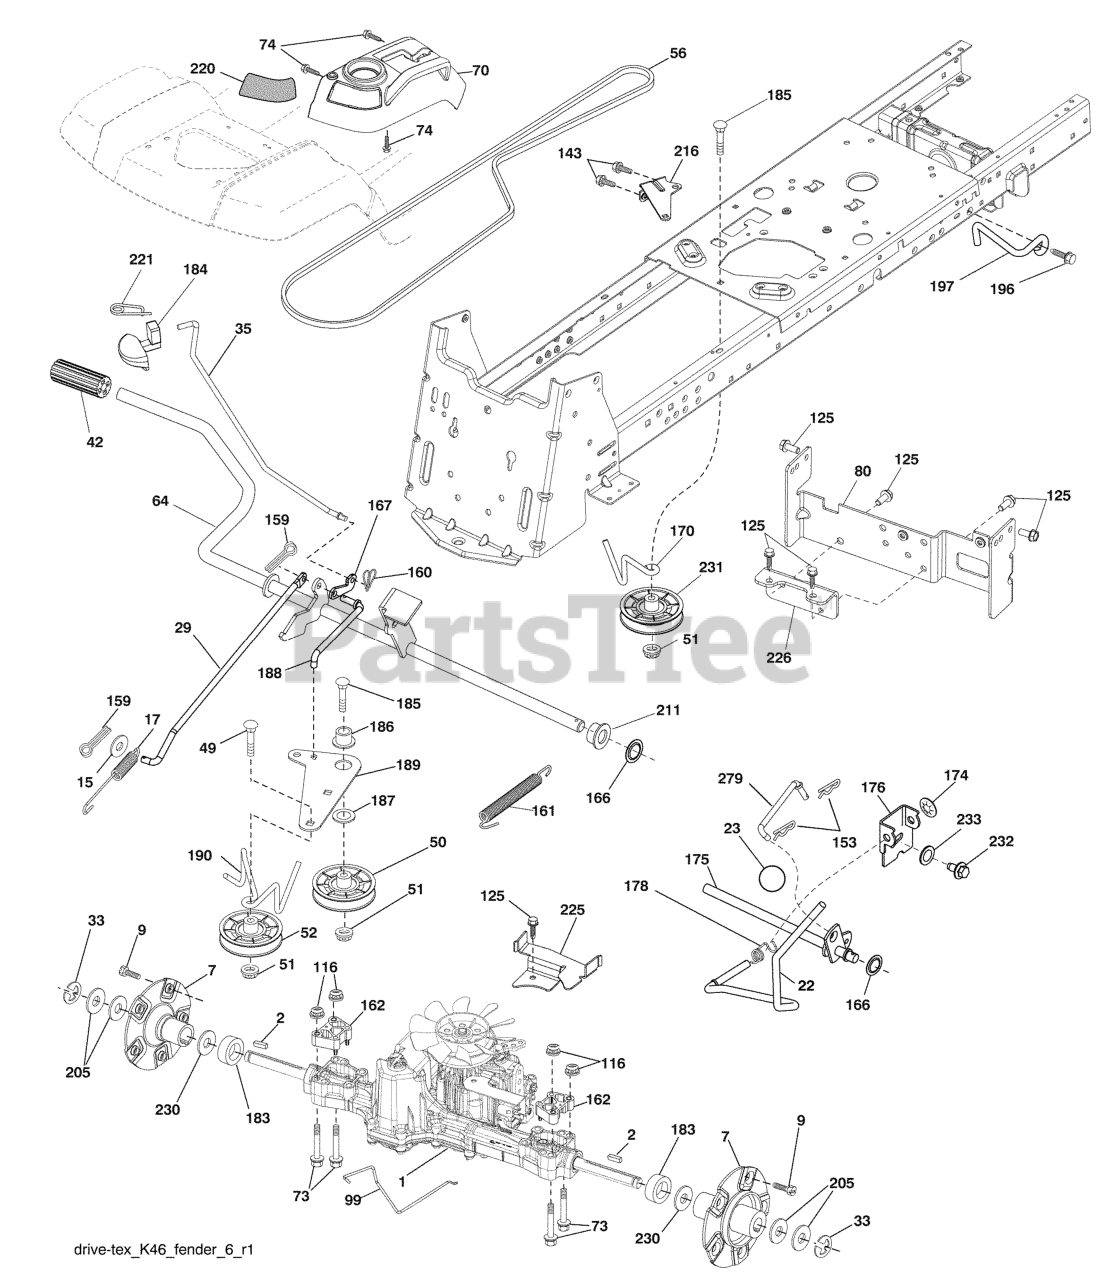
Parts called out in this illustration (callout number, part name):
1	TRANSAXLE(K46AW)22"FS
2	KEY.SQUARE.187X2.500
7	HUB.ASM.WHEEL.REAR.22"
9	HUB BOLT
15	WASHER
17	SPRING.BRAKE.K46.GREEN
22	ROD.SHIFT.FENDER.STGT.
23	KNOB.DELUXE.(PISTOL.GRIP).BLAC
29	ROD.BRAKE.K46
35	ROD.BRAKE.PARKING.GT.H
42	PEDAL COVER T
49	BOLT
50	IDLER.FLAT.910.OFFSET
51	NUT LOCK FLG 3/8-16 UNC
52	IDLER.V-GROOVE.910.OFFSET
56	V-BELT.MOWER.92.40.42/K46
64	SHAFT.ASM.PEDAL.BRAKE.
70	RP CONSOLE.ASM.HYDO.HUSQ.
73	BOLT.HEX.FLNG.5/16-18X3.75
74	SCREW.HI-LO.CONSOLE
80	STRAP.TORQUE.ASM.K46.TG
99	ROD.SPRING.BYPASS.K46.TEX.GT
116	NUT LOCK HEX FLANGE 5/16-18
125	SCREW
143	Screw 5/16-18 x 1/2
153	RETAINER M
159	COTTER PIN
160	RETAINER CLIP
161	SPRING, RETURN LT
162	SPACER.TRANSAXLE.18&22
166	NUT.PUSH.625.2006
167	LATCH.BRAKE.SPRING
170	KEEPER.CENTER SPAN.1.688
174	NUT.PUSH.500.2006
175	SHAFT ASM SHIFT
176	ARM.CLEVIS.ROD.SHIFT
178	SPRING.SHIFT.GT2006
183	SPACER.SPLIT.800X.350
184	HANDLE.PARKG.BRK.HUSQ X667
186	SPACER.RETAINER
187	WASHER 12/32X2X10GA
188	RP.LINK.CLUTCH.GROUND.DRIVE
189	BELLCRANK.GROUND.DRIVE.TEX.
190	KEEPER.BELLCRANK.DRIVE
196	SCREW 3/8-16X1
197	BRKT.ANIT-ROTATION.CLUTCH
211	BUSHING.SHAFT.BRAKE.HAND
216	BRACKET.PULLEY.IDLER.W/TEX
220	REFLECTOR.RH.TEX GT
221	RETAINER.SPRING.CLIP.H
225	KEEPER.BELT.TRANSAXLE.K46
226	BRKT.MOUNT.TORQUE.K46.
230	WASHER.HARDENED
231	IDLER.V-GROOVE.1.688.OFFSET
232	BOLT FIN HEX 7/16-14 X 1
233	WASHER SERRATED
279	LINK.SHIFT.T/A.K46.FEND.TX
